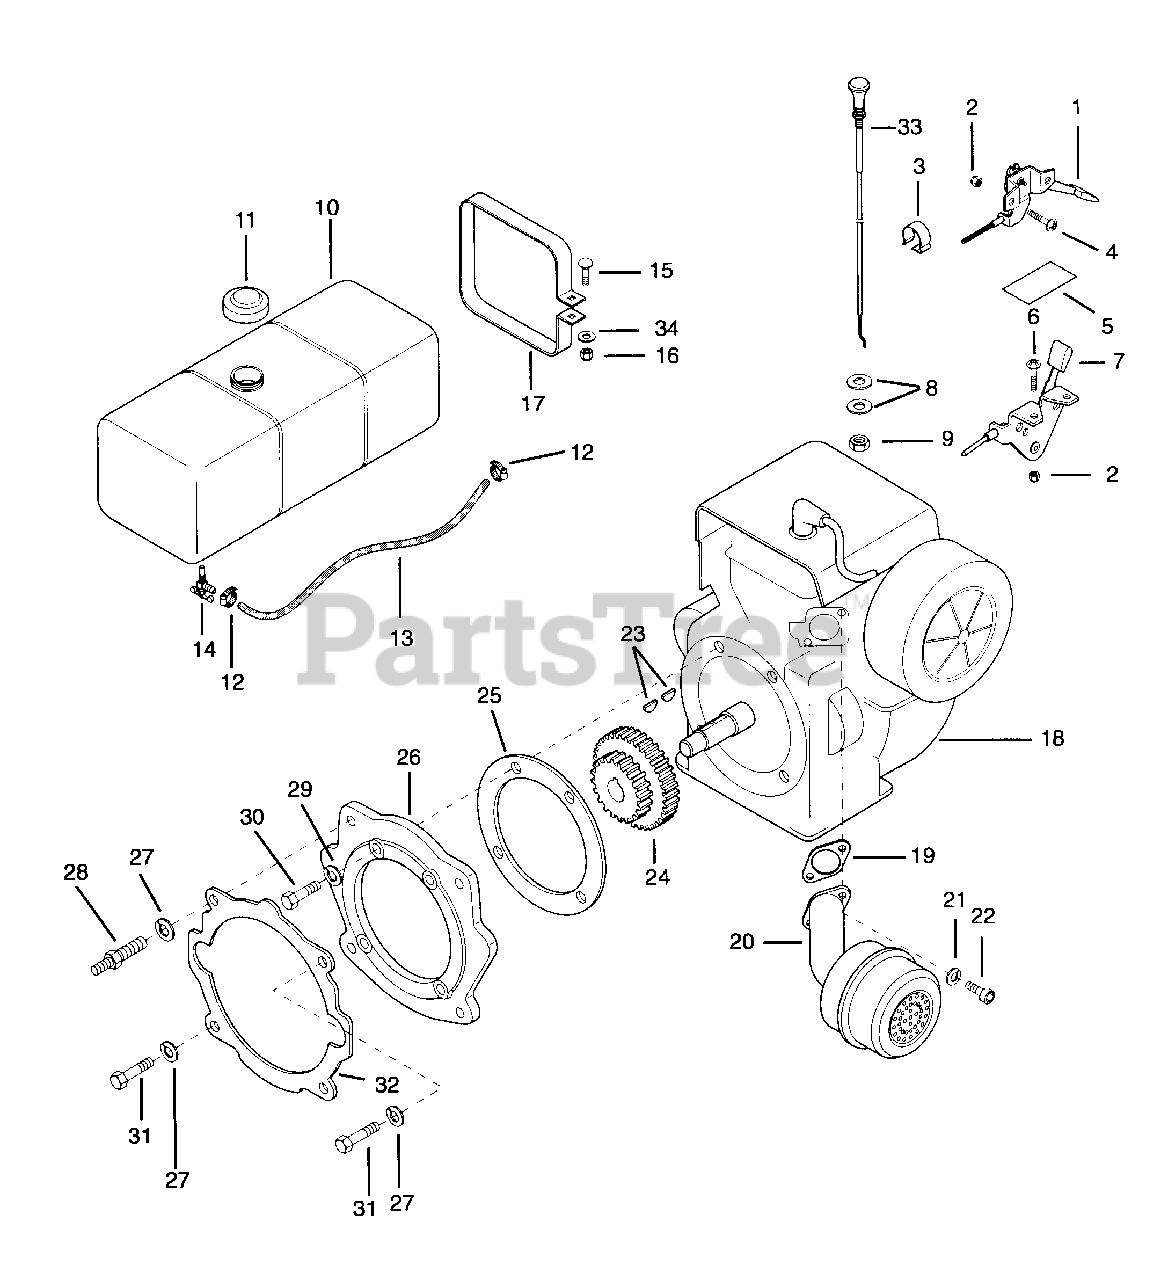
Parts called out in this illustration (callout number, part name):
1	Lever, Control Plated
1	Lever, Throttle Control Plated
2	Nut-Locking Nylon 10-24
3	Clamp
4	Screw-Machine 10-24 x 1.50
5	Decal, Throttle
6	Screw-Machine 10-24 x .50
7	Lever, Throttle Control Plated
7	Lever, Control Plated
8	Washer-Flat-Steel .406 x .812 x .065
9	Nut-Jam .375-24
10	Assembly, Fuel Tank
11	Cap, Gas Tank
12	Hose Clamp
13	Gas Line-Bulk
14	Valve & Strainer
15	Bolt-Round Head Square Neck .25-20 x 1.75
16	Nut-Locking-Center .250-20 Grade 2
17	Strap, Fuel Tank
18	Engine, 12 HP Electric Magnum
18	Engine, 8 HP Electric
18	Engine, 8 HP Recoil
19	Gasket, Exhaust
20	Muffler, 12 HP
21	Washer-Lock .313 x .078
22	Screw-Cap .31-18 x .75
23	Key-Woodruff .16 x .63
24	Gear, 10/12 DP 21/30 Teeth
25	Gasket, Engine to Adaptor
25	Gasket, Engine to Adapter
26	Adapter, Engine
27	Washer-Lock .438 x .133
28	Stud
29	Washer-Lock .375 x .115
30	Bolt-Hex .375-16 x 1.00 Grade 5
31	Bolt-Hex .44-14 x 1.25 Grade 5
32	Gasket, Chassis to Adapter
33	Lever, Choke Control Plated
34	Washer-Flat-Steel .281 x .620 x .065
